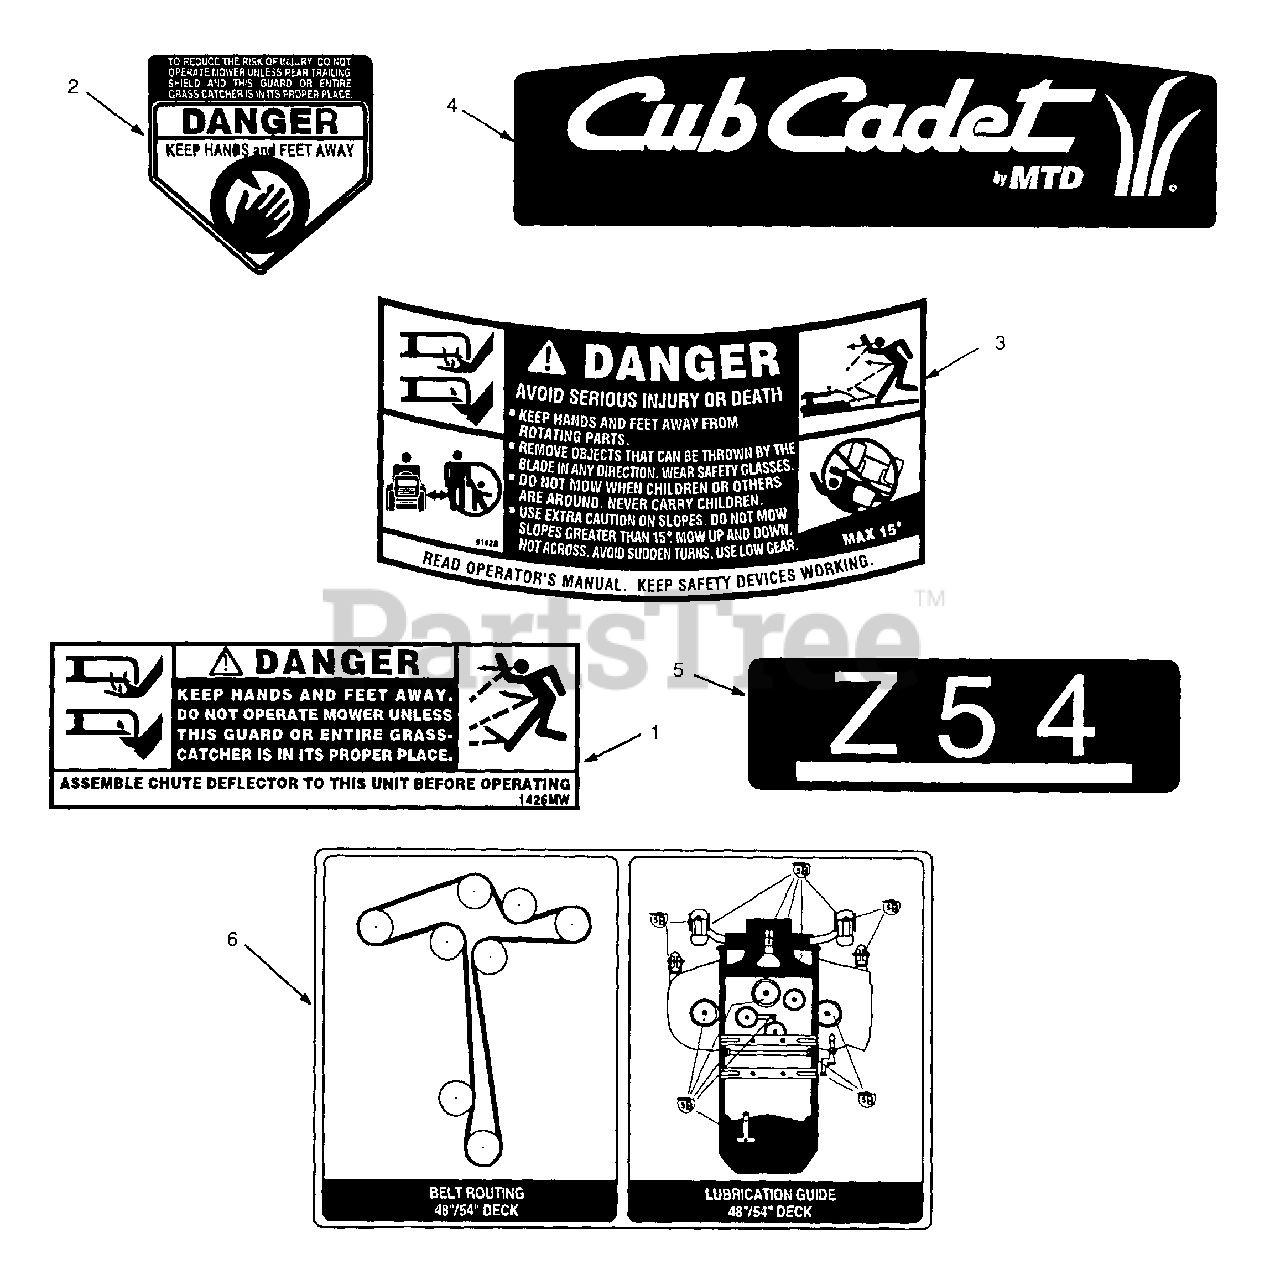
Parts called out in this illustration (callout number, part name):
1	Label, Danger - Top of Deck
2	Label, Danger - Top of Deflector Chute
3	Label, Safety - Top of Deck
4	Label, Model - Back of Seat
5	Label, Safety - Front Steering Console
6	Label, Information - Under Belt Cover
